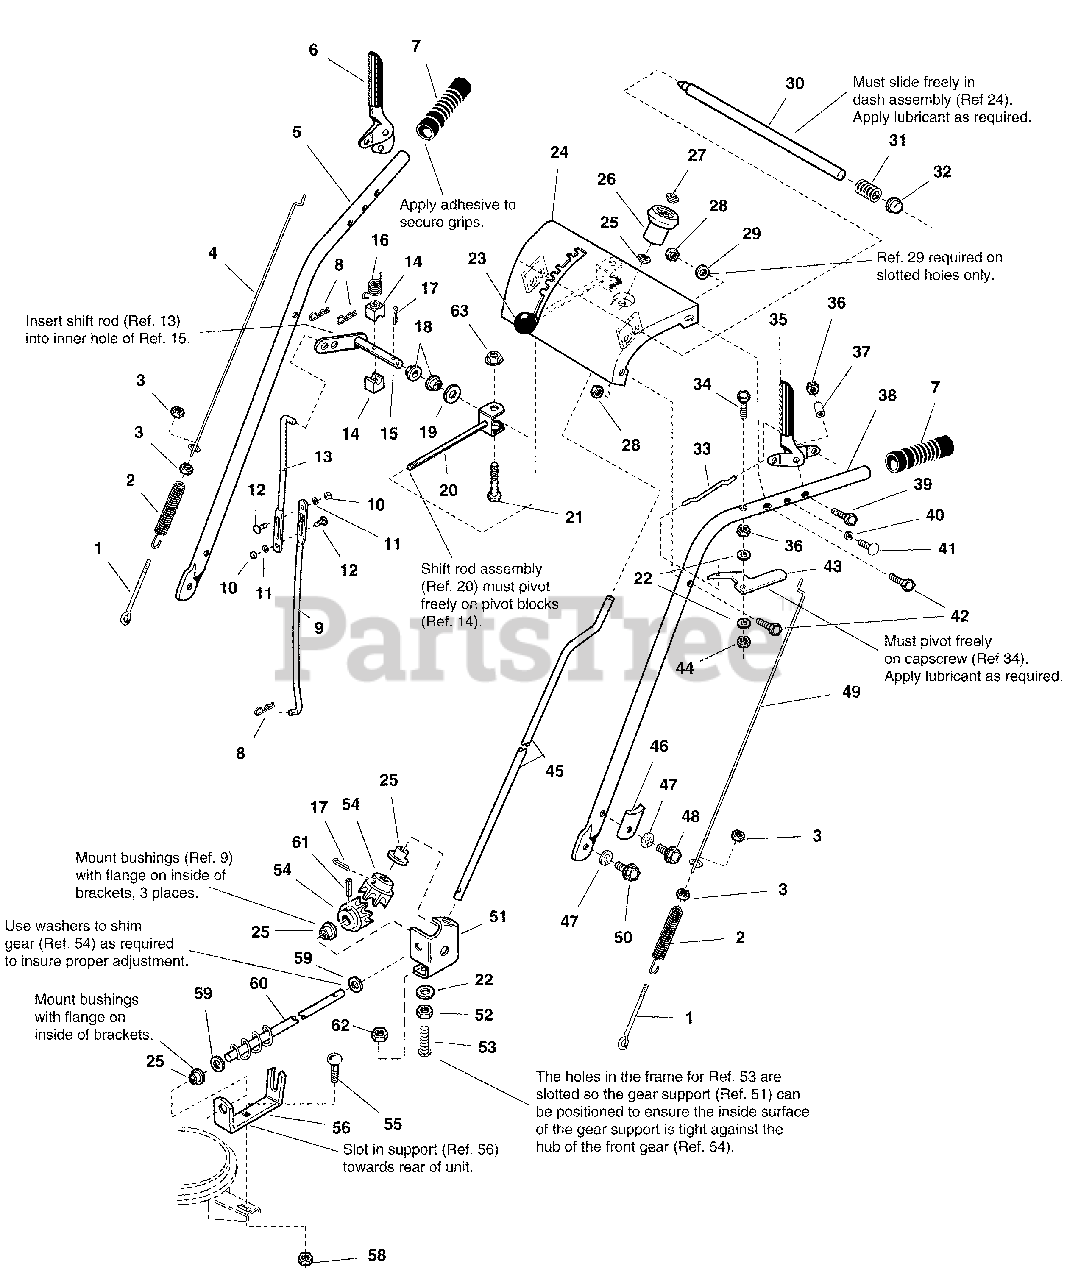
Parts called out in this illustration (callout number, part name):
1	ROD, Control, Lower
2	SPRING, Extension
3	NUT, Hex, #10-24 R.H.
4	CLUTCH ROD, Auger Drive
5	HANDLE, R.H. (Auger Control side)
6	LEVER, Auger Clutch, R.H.
7	GRIP, Black Vinyl, for 1" Tube
8	PIN, Hair
9	ROD, Shift, Lower
10	NUT, Hex Head, 1/4-20
11	LOCKWASHER, Spring
12	CARRIAGE BOLT, 1/4-20 x 5/8
13	ROD, Shift, Upper
14	BLOCK, Pivot
15	ROD & ARM ASSEMBLY, Pivot
16	SPRING, Torsion
17	PIN, Cotter
19	WASHER
20	ROD & CLEVIS ASSEMBLY
21	CAPSCREW, Hex Head Whiz Lock, 1/4-20 x 2-1/4
22	WASHER, Flat 1/4
23	KNOB, Internal Thread, 3/8-16
24	DASHBOARD & SUPPORT ASSAMBLY
25	BUSHING, Nylon
26	KNOB, Chute Control Spinner
27	NUT, Push, 3/8
28	NUT, Hex Lock ESNA Light, 5/16-18
29	WASHER, Flat 5/16
30	ROD & SPRING ASSEMBLY
31	SPRING, Compression
32	NUT, Push for 1/2" Stud
33	ROD, Free hand Control
34	CAPSCREW, Hex Head, 1/2-20 x 1 3/4
35	LEVER, L.H. (Traction Drive Clutch)
36	NUT, Hex, Centerlock, 1/4-20
37	SPACER, Large
38	HANDLE, L.H. (Traction Drive Control side)
39	CAPSCREW, Hex Head, 1/4-20 x 1-1/2
40	SPACER, Small
41	CAPSCREW, Taptite, Pan Head, Torx, 1/4-20 x 3/4
42	CAPSCREW, Hex Head, 5/16-18 x 1-1/2
43	LEVER, Pivot
44	NUT, Hex Lock ESNA Light, 1/4-20
45	ROD, Chute Control
46	CLAMP, Tube, Saddle
47	LOCKWASHER, 5/16
48	CAPSCREW, Hex Head 5/16-18 x 1-3/4
49	CLUTCH ROD, Traction Drive
50	CAPSCREW, Hex Head, 5/16-18 x 3/4
51	SUPPORT, Gear
52	NUT, Push
53	CARRIAGE BOLT, 1/4-20 x 5/8
54	GEAR, Steel, Universal (Supersedes Plastic Gear)
55	CARRIAGE BOLT, 5/16-18 X 3/4
56	BRACKET, Worm Support
58	NUT, KEPS Hex, 5/16-18
59	WASHER, Flat 3/8
60	WORM ASSEMBLY
61	PIN, Spring
62	NUT, Hex Flange, Whiz Lock Small, 1/4-20
63	NUT, Hex Flange 1/4-20 ESNA, Yellow
